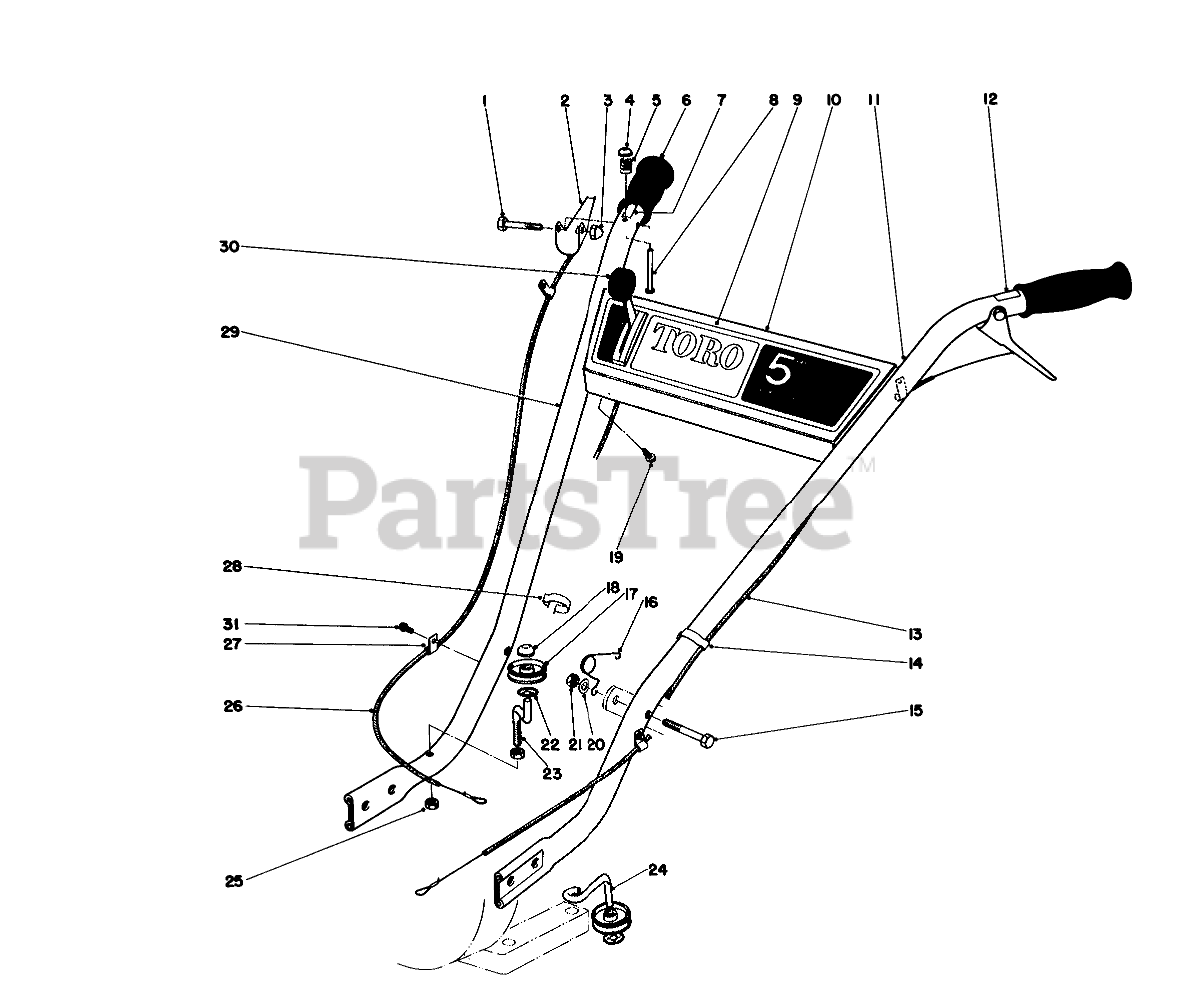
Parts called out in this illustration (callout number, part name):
1	SCREW-HH
2	LIFTBAIL
3	NUT-CAP
4	Push-On
5	COMPRESSION SPRING
6	GRIP-HANDLE
7	Decal-Fwd.
8	LOCK PIN
9	Decal-Escutcheon
10	Escutcheon Panel
11	Handle L.H.
12	Decal Rev.
13	REV CABLE ASM
14	BODEN CLIP
15	SCREW-HH
16	Spring-Torsion
17	Pulley Cable
18	RETAINER PUSH ON
19	SCREW-HWHTF
20	WASHER-PLAIN
21	NUT-LOCK, CONE
22	PUSH ON RETAINER
23	Spindle-Fwd.
24	Spindle-Rev.
25	LOCKNUT
26	FWD CABLE ASM
27	3/16 SUPPORT
28	Boden Clip
29	RH HANDLE
30	THROTTLE CONTROL
31	10 X 1/2 SCREW
